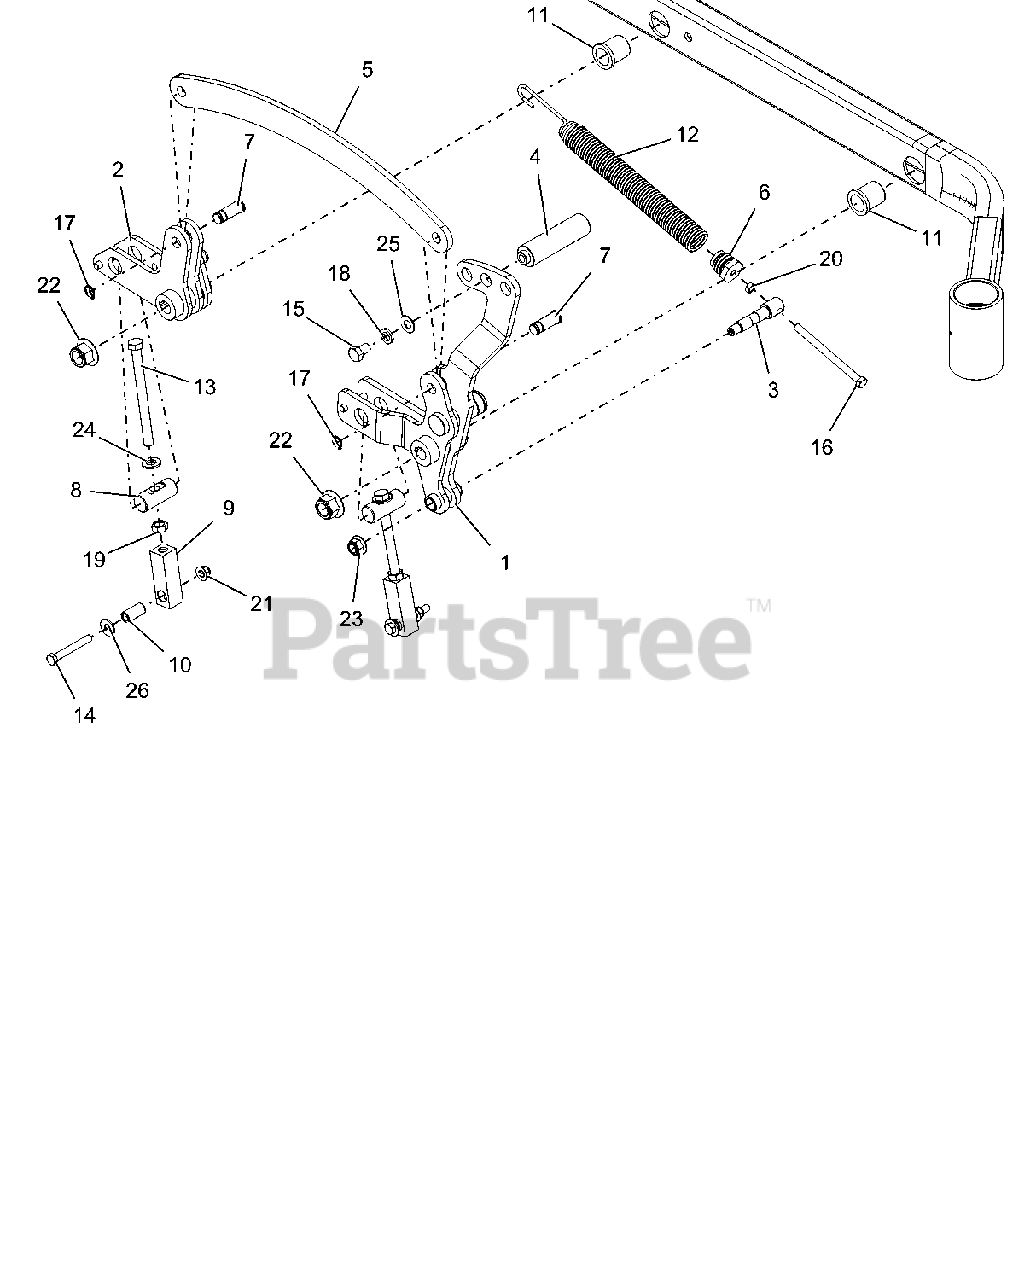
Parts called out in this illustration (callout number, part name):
1	WLDMT, PT400 FRONT RH DECK LIFT ARM (BLACK)
2	WLDMT, PT400 REAR RH DECK LIFT ARM-BLACK
3	TRUNION, SPRG
4	PEDAL, LIFT
5	LIFT, LINK - BLACK
6	PLUG, SPRG
7	PIN, CLEVIS .625 SNAP RING
8	PIN, DECK LIFT
9	LINK, DECK LEVELING
10	SPCR, DECK LEVELING
11	BSHG-FLG 1.00X1.25X1.5X1.5
12	SPRG, DECK LIFT
13	BLT-HEX .50-13X6.00 2.5 THD GR5 YWZC
14	BLT-HEX .38-16X2.75 GR8 YWZC
15	BLT-HEX .50-13X.75 GR5 YWZC
16	BLT-HEX .38-16X5.00 GR5 YWZC
17	RG-RTNG-EXT .625x.050
18	WSHR-LK .50X.125 REG YWZC
19	NUT, JAM .500-13 YWZC
20	NUT, JAM .375-16 YWZC
21	NUT-LK-NYL-FLG .38-16 YWZC
22	NUT-LK-NYL-FLG .75-10 YWZC
23	NUT-LK-NYL-FLG .50-13 YWZC
24	WSHR-FL-STL .557X1.040X.102 YWZC HARD
25	WSHR-FL-STL .505X1.00X.062 YWZC
26	WSHR-FL-STL.438X1.00X.083 YWZC
